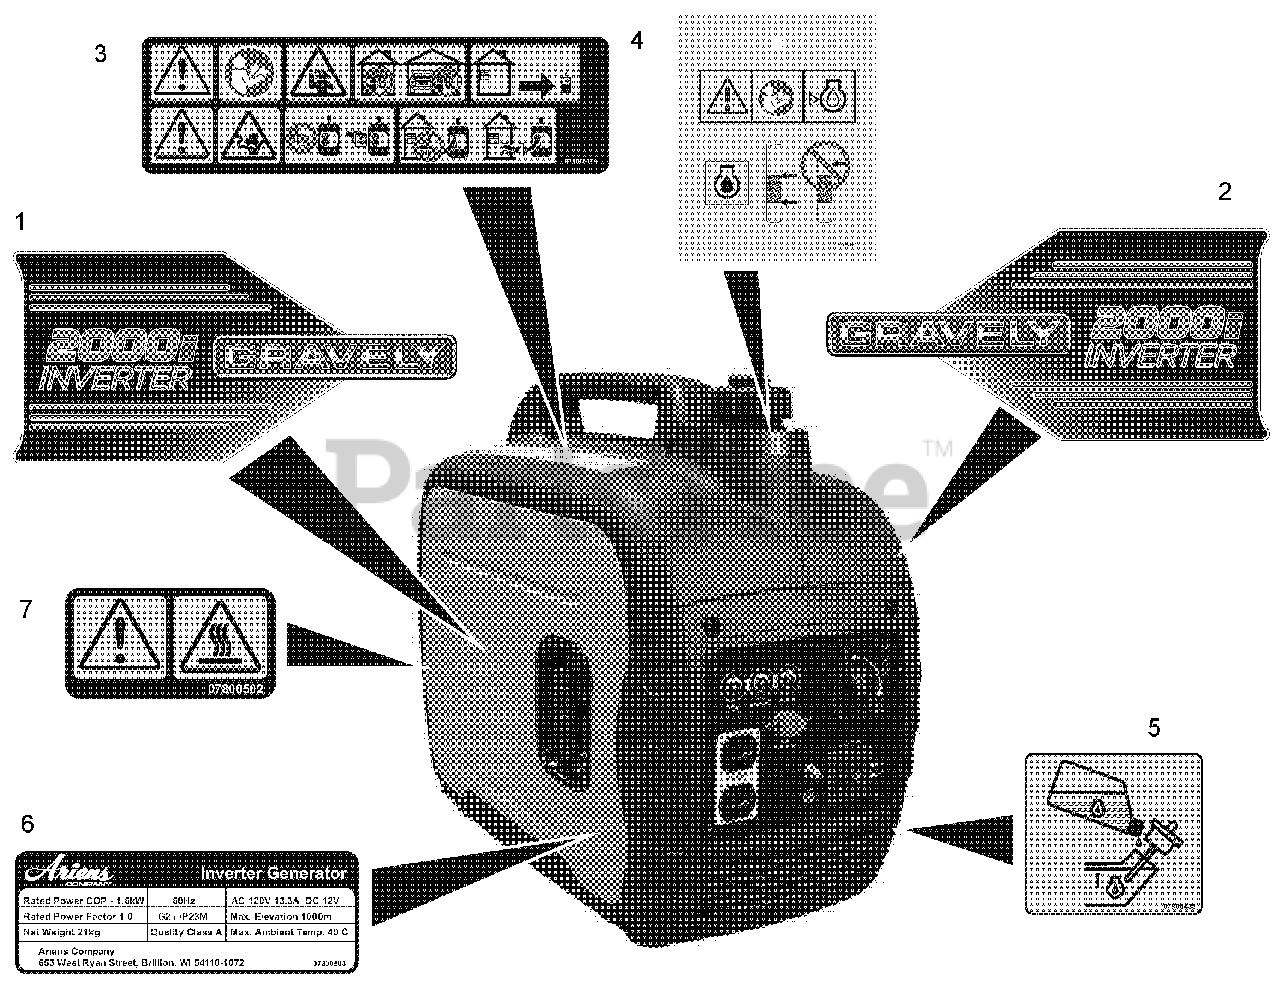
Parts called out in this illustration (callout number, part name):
1	DECAL, STYLE RH GRAVELY
2	DECAL, STYLE LH GRAVELY
3	DECAL, WARNING
4	HANG TAG, OIL DRAIN
5	DECAL, ADD OIL
6	DECAL, SPEC LABEL
7	DECAL, HOT SURFACE
